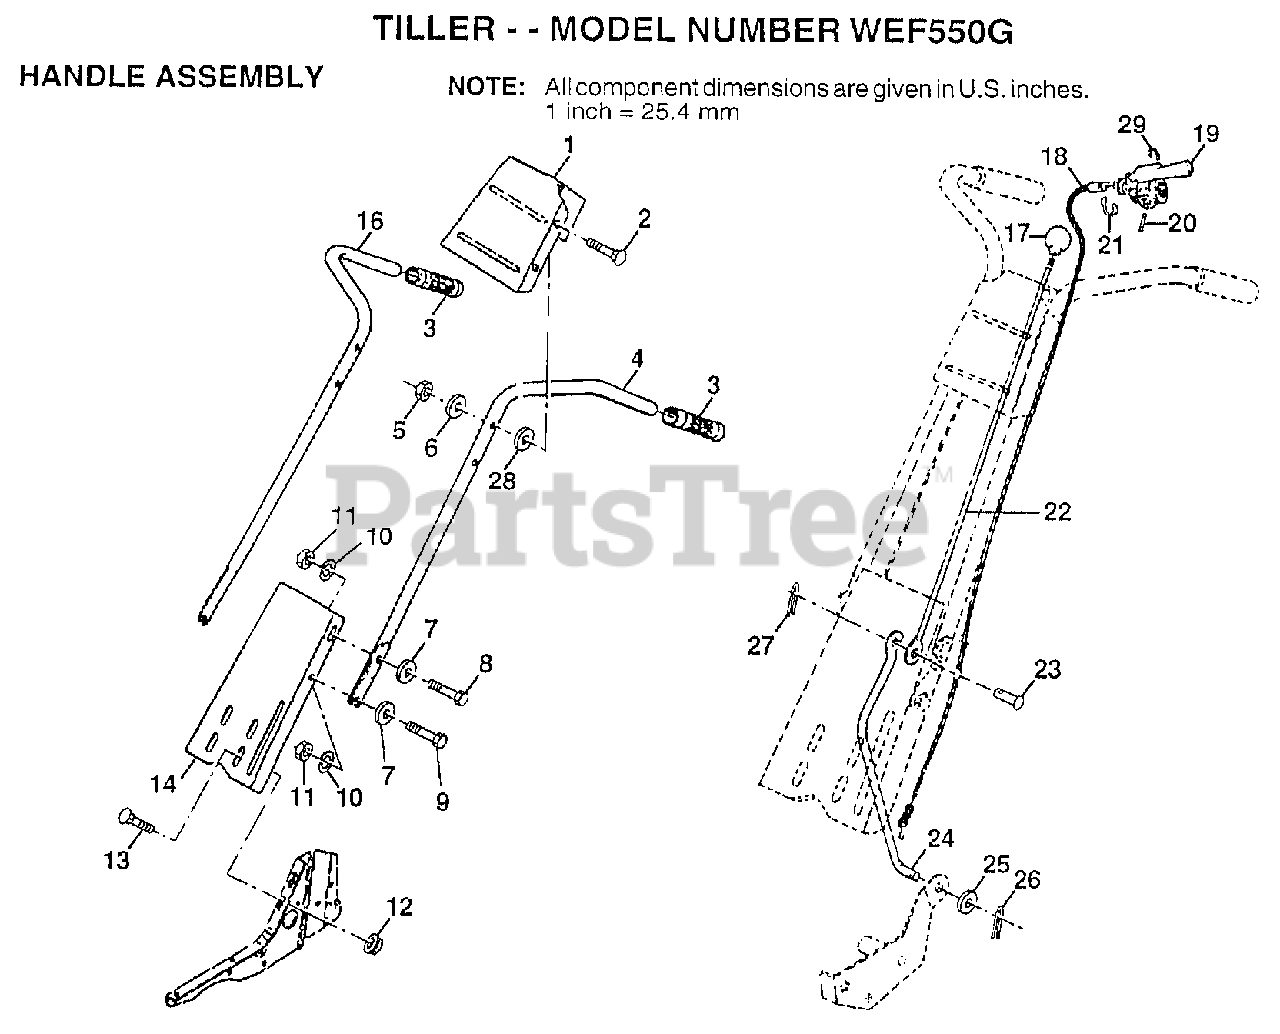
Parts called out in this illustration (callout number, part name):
1	BRACKET.HDLE.TILL
2	BOLT
4	HANDLE.LH TILLER
6	WASHER
7	WASHER
9	BOLT
10	LOCKWASHER
11	NUT.HEX.5/16-18
12	NUT
13	BOLT
14	PANEL.HANDLE.PNT.
16	"HANDLE-RH,TILLER"
17	KNOB T(3/8 HOLE)
18	CABLE CLUTCH T
19	LEVER CONTRL TINE
20	"PIN PIVOT,GROOVED"
21	E-RING
22	ROD REVERSE TI
23	RIVET.RD.HD.DRILL
24	REVERSE ROD TI
25	WASHER
26	COTTER PIN
28	WASHER
29	RETAINER RING
